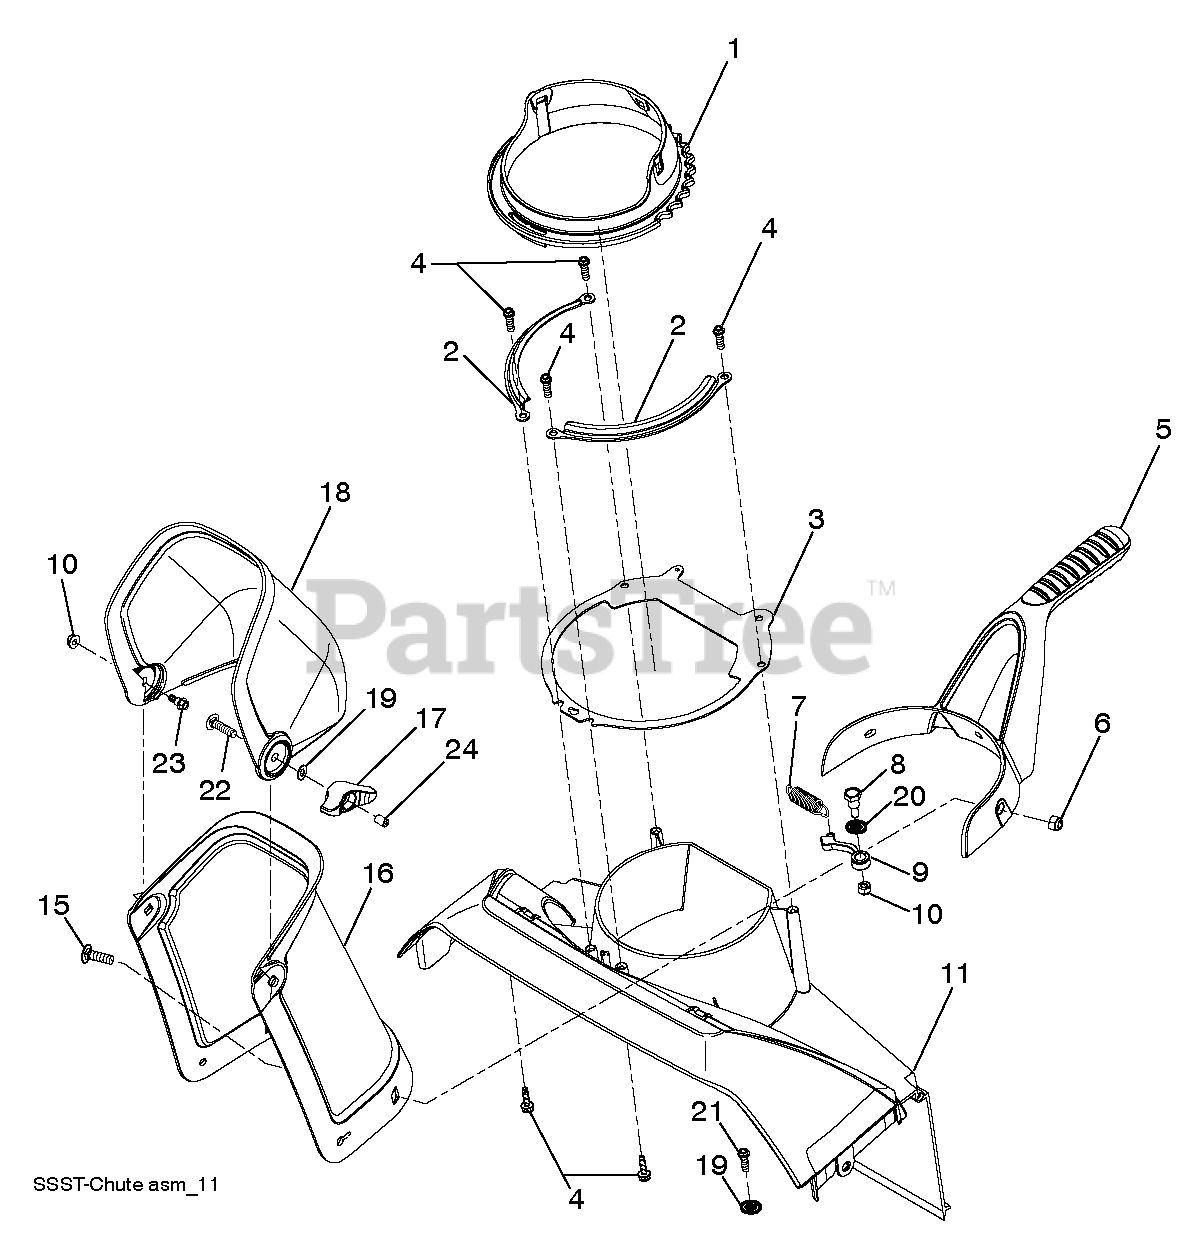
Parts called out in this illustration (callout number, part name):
1	CHUTE.RATCHETING.PLASTIC.W/GRV
2	PLATE.CHUTE.RETAINER
3	PLATE.CHUTE.BASE
4	SCREW.HX.13X.750
5	HANDLE.CHUTE.BLACK
6	LOCKNUT-FLANGE 5/16-18
7	SPRING.RATCHET.ARM
8	SHOULDER BOLT ST
9	ARM.CHUTE.RATCHET
10	NUT
11	PLENIUM.AUGER.POULAN PRO.BLACK
15	BOLT.CARR.5/16-18X1.BLACK
16	CHUTE.SINGLE.STAGE.SNOW.BLACK
18	DEFLECTOR.CHUTE.BLACK
20	WASHER.13/32X1-1/2X16GA
21	BOLT.HEX.HD.WASHER.5/16-18X.75
22	BOLT.CARRIAGE.5/16-18
23	BOLT.SHOULDER.HEX.HD.1/4-20
24	PLUNGER CAP
